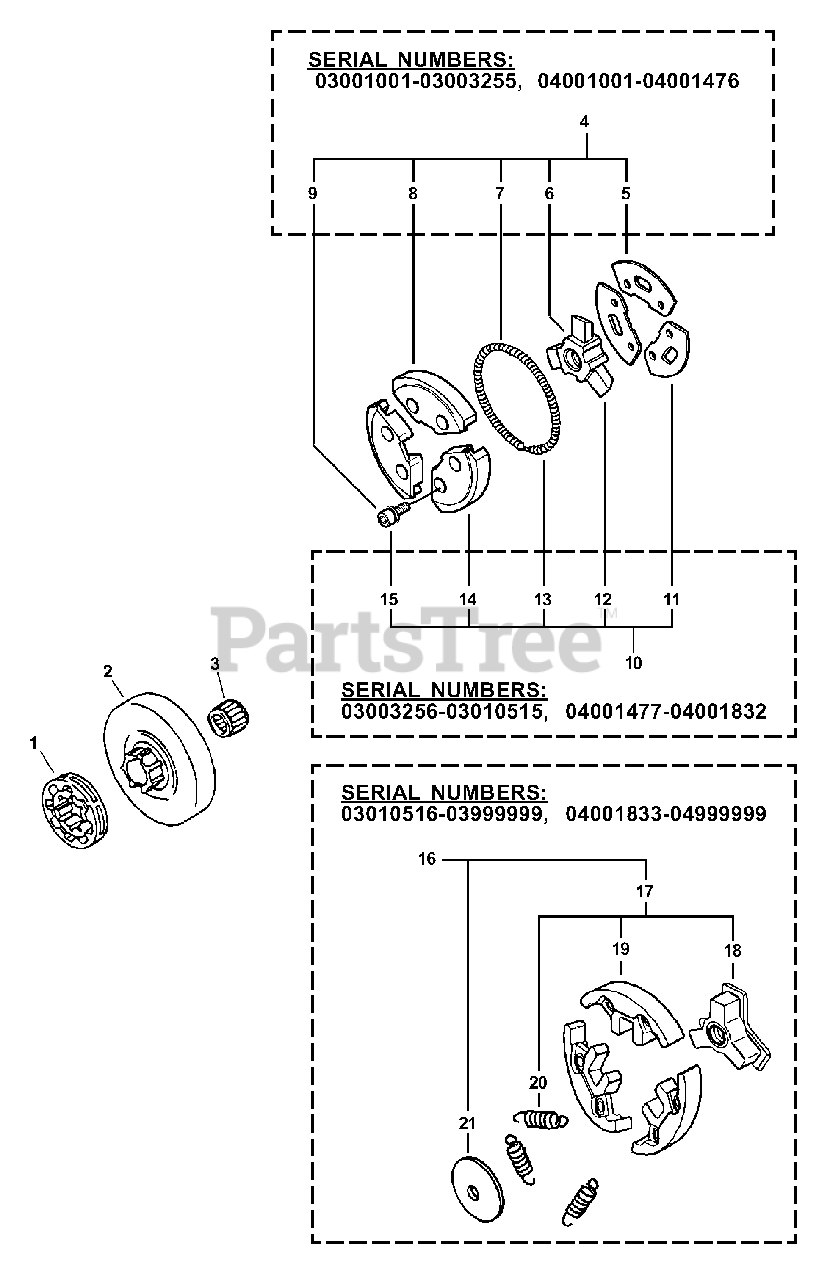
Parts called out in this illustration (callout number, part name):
1	SPROCKET, RIM
2	DRUM, CLUTCH
3	BEARING, NEEDLE
4	CLUTCH ASSY
5	PLATE, CLUTCH
6	HUB, CLUTCH
7	SPRING, CLUTCH
8	CLUTCH SHOE SET
9	SCREW - 4X6
10	CLUTCH ASSY
11	PLATE, CLUTCH
12	HUB, CLUTCH
13	SPRING, CLUTCH
14	CLUTCH SHOE SET
15	SCREW - 4X6
16	CLUTCH ASSY
17	CLUTCH ASSY
18	HUB, CLUTCH
19	CLUTCH SHOE SET
20	SPRING, CLUTCH
21	PLATE, CLUTCH
